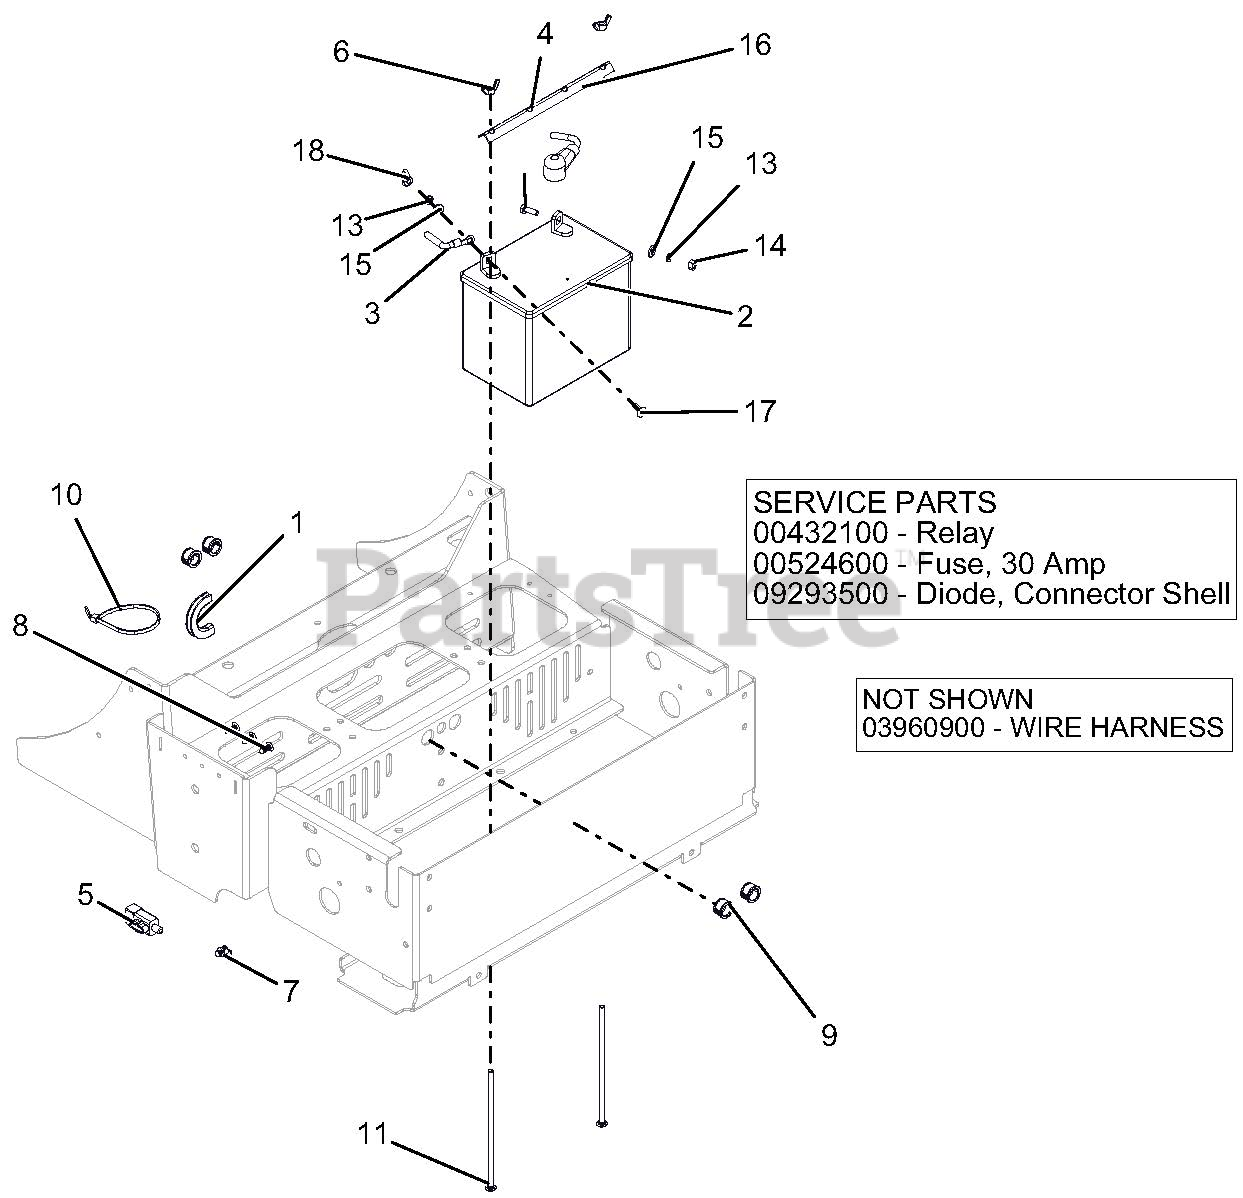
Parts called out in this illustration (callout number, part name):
1	STRIP, COWL - 1.50 LG
2	BATTERY, 300 CCA 10U1L
3	CABLE, NEGATIVE BATTERY 35.00"
4	HOLD DOWN - BLK
5	SWITCH, SNAP IN -N.O./N.O
6	NUT-LOCKING WING 1/4-20
7	CABLE TIE W/ TREE (.25 HOLE)
8	RIVET, .25 NYLON PANEL
9	BUSH, PANEL SNAP .687X.875X.56
10	CABLE, TIE 5.50 LG
11	BLT-RDHDSQNK .25-20X7.50 G2 YWZC
12	BLT-HEX .25-20X.75 GR5 YWZC
13	WSHR-LK .25X.062 REG YWZC
14	NUT-HEX .25-20 YWZC
15	WSHR-FL-STL.281X.62X.065 YWZC
16	CABLE, POS BATT W/ BOOTS 6 X 35
17	BLT-RDHDSQNK .25-20X.75 G5 YWZC
18	NUT-WING .250-20 YWZC
19	Relay
20	Fuse, 30 Amp
21	Diode, Connector Shell
